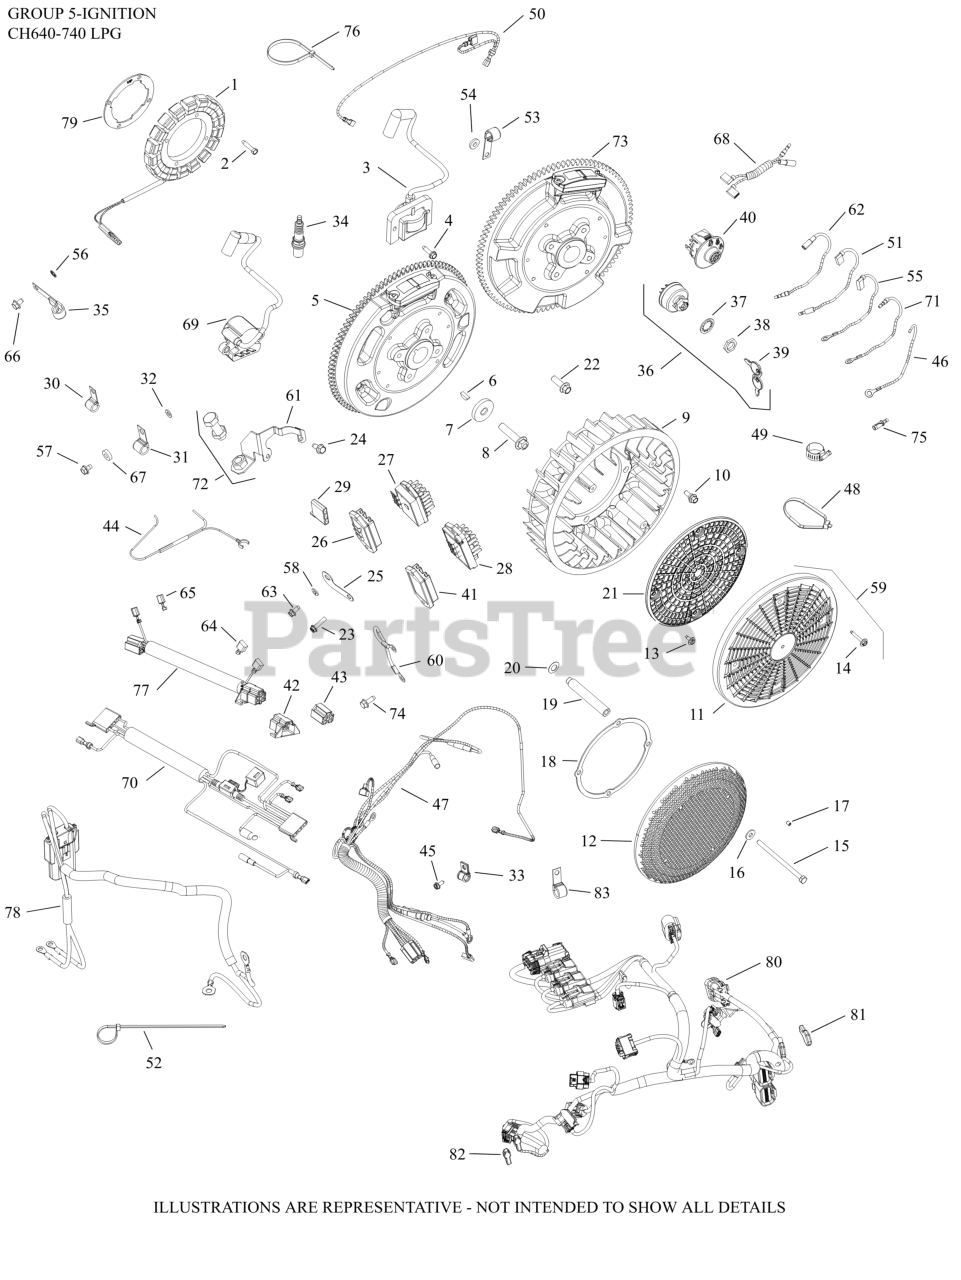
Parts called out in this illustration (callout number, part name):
1	KIT, 15 / 20 AMP STATOR
2	SCREW, THREAD FORMING
4	SCREW, THREAD FORMING
5	FLYWHEEL ASSEMBLY (LW)
6	KEY, 3/16" X 5/8"
7	WASHER, FLAT 13/32"
8	SCREW, FLG M10X1.5X45-USE 25 086 361-S
9	FAN-USE 24 755 253-S
10	BOLT, SHOULDER
13	SCREW, SEMS DOG POINT
21	SCREEN,GRASS LOW PRFLE W/O HOLE
23	SCREW, HEX FLANGE HI-LO
26	REGULATOR/RECT 12/15A HALF-WAVE STD
29	CONNECTOR
32	WASHER, FLAT 1/4" (O.D. 1/2")
34	SPARK PLUG, RFI
39	KEY, SET OF 2
40	KIT, KEY SWITCH (SNAP-IN)
47	HARNESS, WIRING ASSEMBLY
49	CLAMP, HOSE
51	LEAD, OIL SENTRY
55	LEAD, 20/25 AMP B+
58	WASHER, LOCK
69	MODULE SPARK ADVANCE (DSAI) ASSEMBLY
70	HARNESS, WIRING (DSAI LP/NG)
71	LEADS (UNIVERSAL GROUND)
NI	CLIP, CABLE (KM)
